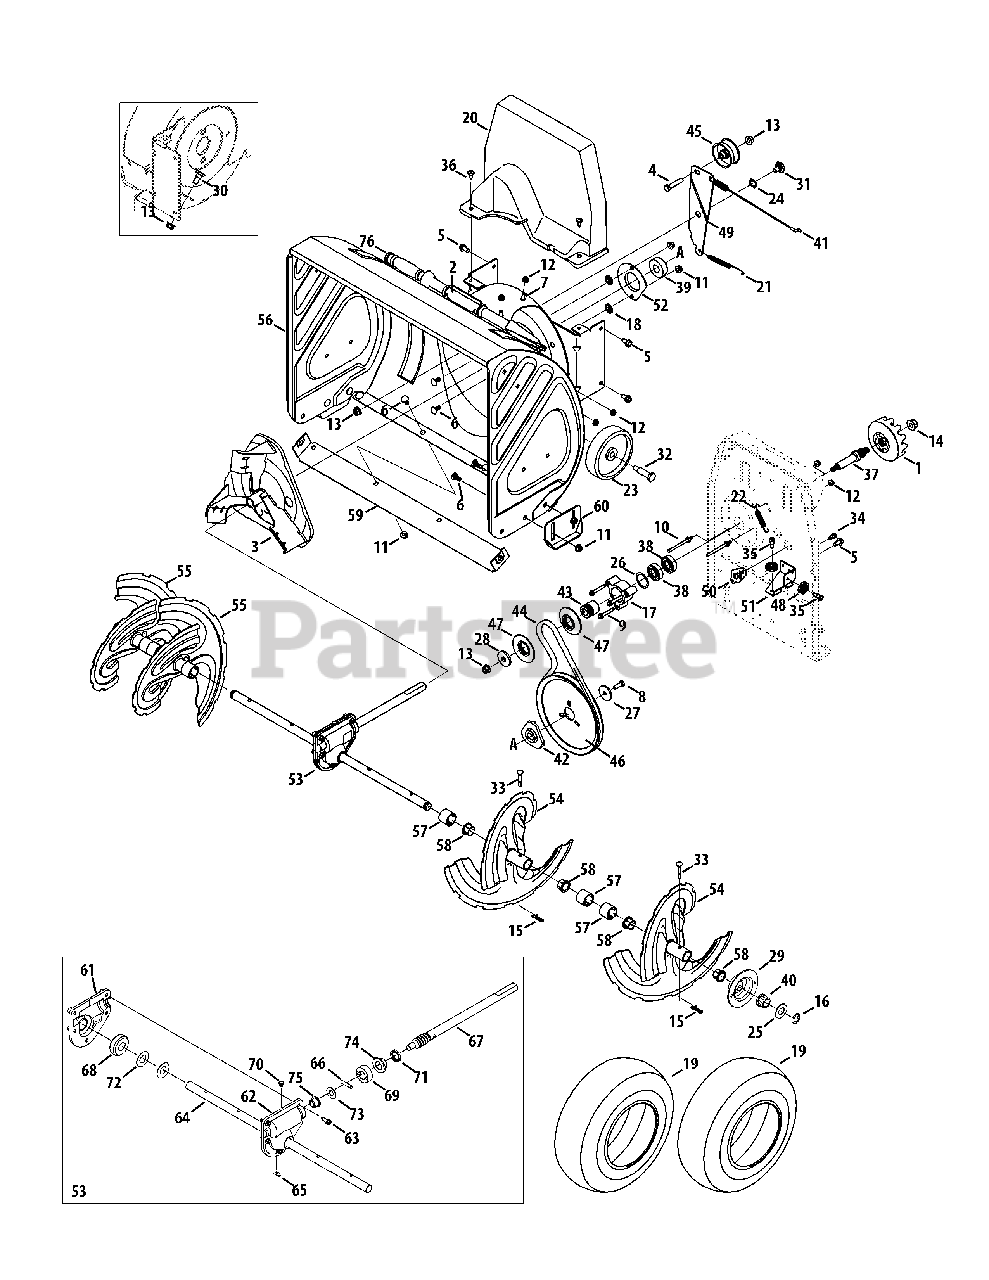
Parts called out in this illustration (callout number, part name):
1	Clutch Assembly
2	Clean-Out Tool Mount
3	Impeller Assembly, 12"
4	Hex Cap Screw, 3/8-16 x 1.75
5	Hex Washer Screw, 5/16-18 x .750
6	Carriage Bolt, 5/16-18 x 0.75
7	Carriage Screw, 1/4-20 x 0.75
8	Hex Cap Screw, 5/16-24 x .875
9	Self-tapping Screw, 1/4-20 x 1.625
10	Belt Keeper, .25 Dia. x 2.64
11	Flange Lock Nut, 5/16-18
12	Flange Lock Nut, 1/4-20
13	Flange Lock Nut, 3/8-16
14	Flange Lock Nut, 1/2-13
15	Bow-Tie Cotter Pin, 72
16	E-Ring, .750
17	Bearing Cup
18	Nut, Push-on, .25 Dia.
19	Snow Sock, 13" x 4"
20	Snow Cover Housing
21	Extension Spring, .38 OD x 4.59
22	Extension Spring, 2.675
23	Deck Wheel, 5.0 x 1.38
24	Wave Washer, .625 x .885 x .015
25	Flat Washer, .76 x 1.49 x .06
26	Washer, 1.25 x 1.57 x .01
27	Flat Washer, .340 x 1.50 x .150
28	Flat Washer, .45 x 1.5 x .172
29	Hex Bearing Housing
30	Shoulder Screw, 3/8-16 x .496 x .336
31	Screw, Shoulder, .625 x .17 x 3/8-16
32	Shoulder Bolt, .496 x 1.525
33	Shear Pin, .25 x 1.50
34	Shoulder Screw, 1/4-20 x 0.50
35	Shoulder Bolt, 1/4-28 x .342 x .335
36	Shoulder Screw, 1/4-20
37	Drive Spindle Plate
38	Ball Bearing, 17 x 40 x 12
39	Bearing, Ball, .75 x 1.85
40	Hex Flange Bearing
41	Auger Clutch Cable
42	Pulley Adapter, .75 DIA
43	Spacer, .670 ID x 1.185 OD
44	Belt, 34.56
45	Idler Pulley, 2.46 OD
46	Auger Pulley, 8.1 x .5
47	Pulley, Half, 4L-V x 2.600
48	Roller Cable
48	Cable Guide Bracket
49	Auger Idler Bracket
50	Snow Cable Bracket
51	Cable Bracket
52	Bearing, 1.85 ID
53	Gearbox Ass'ly, 26", includes 38-52
54	Spiral Assembly, LH
55	Spiral Assembly, RH
56	Auger Housing Assembly, 26"
57	Spacer, 1.25 x .75 x 1.00
58	Bushing, Flange, .800 x .910
59	Shave Plate, 26"
60	Skid Shoe, Standard
61	Reducer, RH
62	Reducer, LH
63	Screw, 1/4-20 x 0.750
64	Auger Axle, 26"
65	Key, Hi-Pro, 3/16 x 5/8
66	Dowel Pin, .25 x 1.25
67	Worm Shaft, .75
68	Gear Worm, 20T
69	Collar Thrust, .756 x .600
70	Plug, 1/4 x .437
71	Oil Seal, .75 x 1.131 x .188
72	Washer, Flat, .760 x 1.50
73	Washer, Flat, .51 x 1.12
74	Bearing, Flange, .75 x 1.00 x .59
75	Bearing, Flange, .50 x .75 x .59
76	Clean-Out Tool
